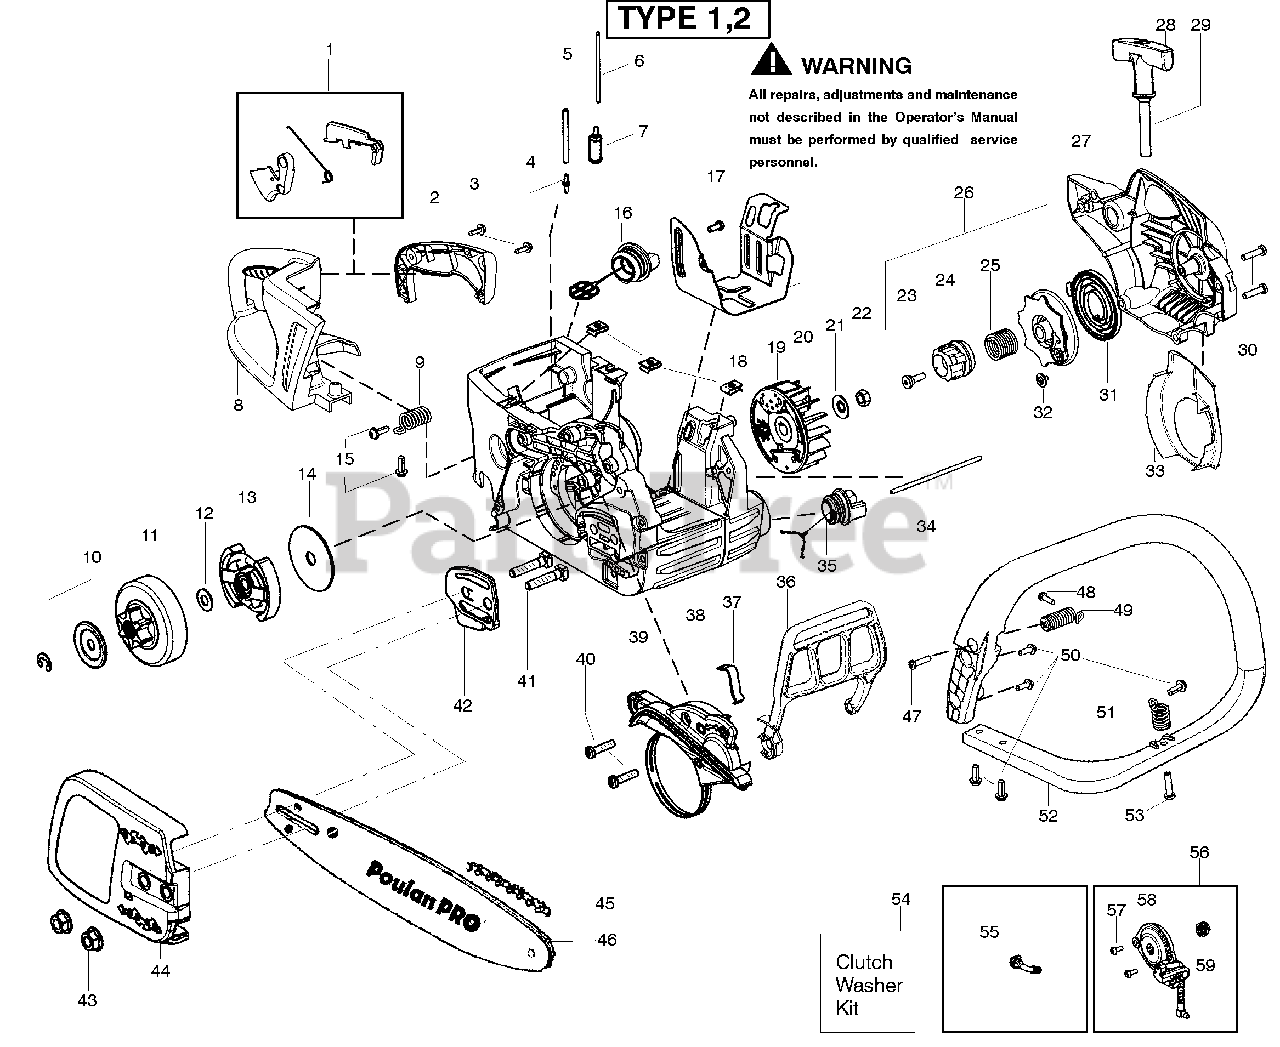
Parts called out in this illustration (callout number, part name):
1	Kit-Trigger/Lockout
4	Fitting-Fuel line
5	Kit-Fuel Line (Large)
6	Kit-Fuel Line (Small)
7	Assy-Fuel Pick Up
8	Handle-Rear
9	Spring-Rear Isolator
10	Kit-Clutch Washer
11	Assy-Clutch Drum 3/8"
12	Kit-Clutch Washer
14	Washer-Large Clutch
16	Assy-Fuel Cap w/ret
18	Nut-"U" type speed
19	Assy-Flywheel
21	Washer-Flywheel
23	Screw-Shoulder
24	Starter Hub-EPS
26	Kit- EPS Starter Pulley
28	Handle-Starter
31	Spring-Starter
34	Assy-Oil Vent
35	Assy-Oil Cap w/ret.
36	Handguard
37	Spring-Handguard
38	Assy-Chassis
39	Kit-Chainbrake
44	Assy-Clutch Cover
45	Accy-18" Chain
49	Assy-Rear Iso. Spring
51	Assy-Front Iso. Spring
54	Kit-Clutch Washer
55	Assy-Oil Pick Up
56	Kit-Oil Pump
58	Assy-Oil Pump
